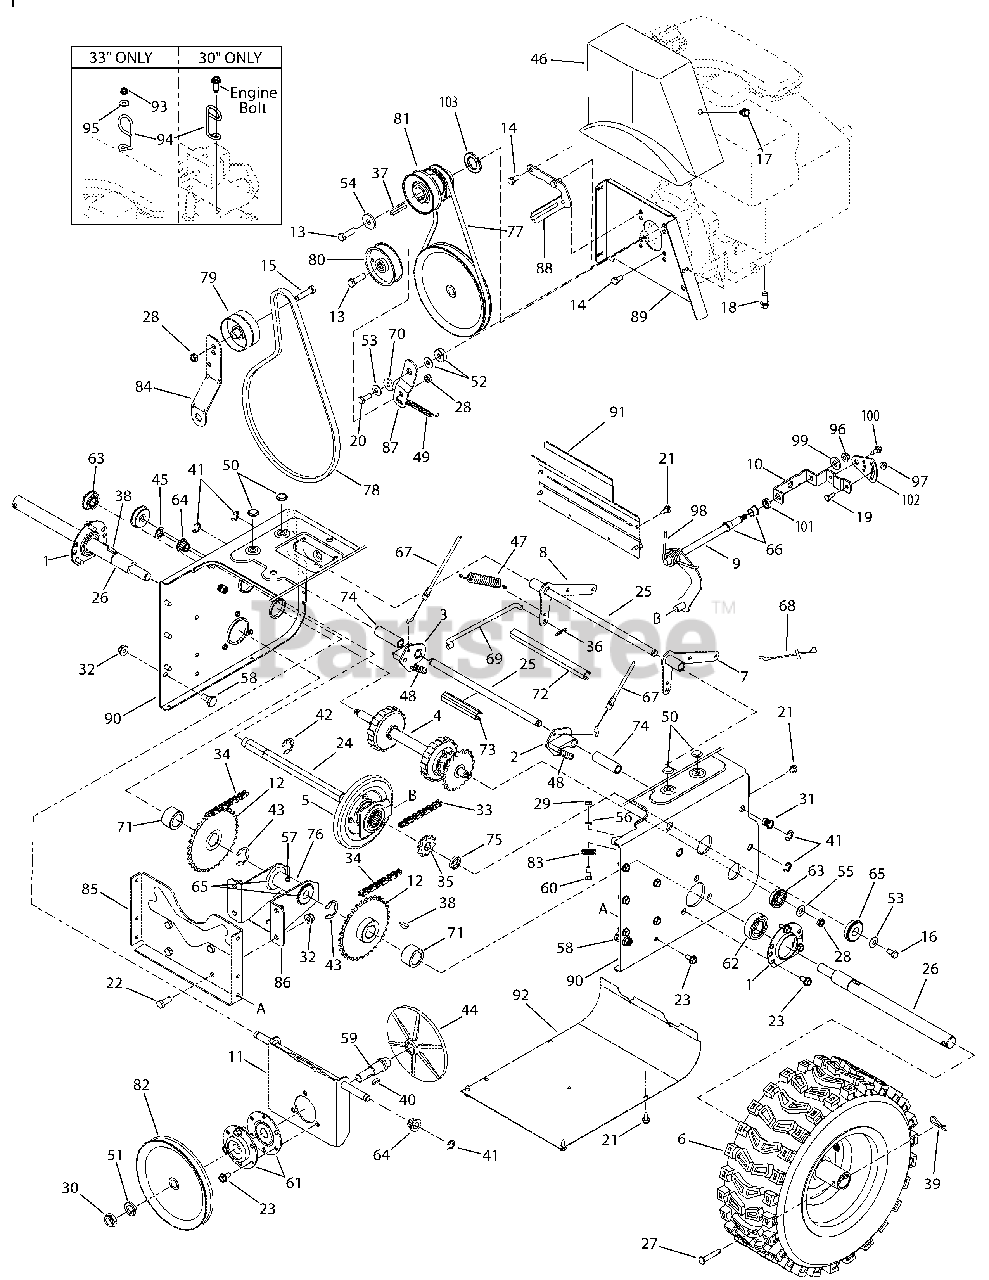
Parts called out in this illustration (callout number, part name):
1	Housing, Bearing
2	Dogg, Steering Drive, LH
3	Dogg, Steering Drive, RH
4	Shaft Assembly, Steering
5	Assembly, Friction Wheel
12	Sprocket, 32T
13	Screw, Hex Cap, 3/8-24 x 1.25 Gr8
14	Screw, Hex Cap, 5/16-24 x .625 Gr5
15	Screw, 3/8-24 x 1.50
16	Screw, Hex Cap Lk, 5/16-18 x .625 Gr5
17	Screw, Hex Tapp, 5/16-18 x .5
18	Screw, Hex Sems Tapp, 3/8-16 x 1.0
19	Screw, Hex, 1/4-20 x .620
20	Scrw, Hx , 5/16-24 x 1.25 Gr5 - 30" ONLY
20	Scrw, Hx Lk, 5/16-24 x .875 Gr8 - 33" ONLY
21	Screw, Hex Wash.
22	Screw, Hex Cap, 3/8-16
23	TT Screw, 5/16-18 x .750
24	Shaft, Hex Drive
25	Shaft, Actuator
26	Axle, Wheel
27	Pin, Clevis
28	Nut, Hex Insert Jam Lock
29	Nut, Hex, 1/4-28 GR5
30	Nut, Hx Insert Jam Lk
31	Nut, Insert 3/8-16
32	Nut, Hx Flnge Insert Lk
33	Chain, Endless, #41 x 36L
34	Chain, #420 x 40L
35	Sprocket, #41 x 10T
36	Pin, Internal Cotter
37	Key, Square, 1/4 x 1.5
38	Key, Woodruff
39	Pin, Internal Cotter
40	Key, Hi-Pro, 3/16 x 5/8
41	E-Ring
42	Ring, Retaining
43	Ring, Retainer
44	Plate, Drive
45	Nut, Speed
46	Cover, Belt
47	Spring, Extension
48	Spring, Extension
49	Spring, Extension, .375 x 3.18
51	Washer, Lock, 5/8
52	Spacer, .331 x 1.01 x .36 - 30" ONLY
52	Washer, Flat, .349 x .879 x .063 - 33" ONLY
53	Washer, Belleville, .34 x .872 x .06
54	Washer, Flat, .406 x 1.25 x .157 HT
55	Wash, .406 x .875 x .059
56	Washer, Lock, 1/4
57	Fitting, Lube, 3/16 Drive
58	Screw, Shldr., .498 x .34
59	Spindle, Drive Plate
60	Screw, Hex Shldr., 1/4-28
61	Ass’y, Bearing/Housing
62	Bearing, Self Aligning
63	Bearing, Ball
64	Bearing, Hex Flange
65	Bearing, Ball
66	Bush, Flg, .5 ID x .627 OD
67	Cable, Steering
68	Cable, Auger Idler
69	Rod, Drive Clutch
70	Spacer, Shoulder
71	Spcr., 1.0 ID x 1.50 OD
72	Spcr., .51 ID x 7.895 Lg.
73	Spcr., .51 ID x 3.66 Lg.
74	Spcr., .514 x .632 x 2.44
75	Spacer, .675 x 1.0 x .23
76	Spcr, .6725 x 1.125 x 2.48
77	V-Belt, 3/8 x 34.4 - 30" ONLY
77	V-Belt, 3/8 x 35.5 - 33" ONLY
78	V-Belt, 1/2 x 42.0 - 30" ONLY
78	V-Belt, 1/2 x 44.0 - 33" ONLY
79	Idler, Flat, 2.75 OD
80	Pulley, Flat Idler, 3.0 OD
81	Pulley, Dbl, 3.25 OD
82	Pulley, Drive
83	Roller, Cable
84	Brkt., Idler, Auger
87	Bracket, Idler, Drive
93	Nut, Flange Lock, 1/4-20 GrF
94	Guide, Control Cable
95	Washer, Flat, .28 x .74 x .063
96	Nut, Hx Flnge Insert Lk, 5/16-18 GrF
97	Nut, Hx Flnge Insert Lk, 1/4-20 GrF
98	Spring, Torsion
99	Washer, Flat, .469 x .875 x .105
100	Screw, Shoulder, .368 x .113:1/4-20 TT
101	Spacer, .5151 x .75 x .22
103	Spacer, 1.02 x 1.63 x .1425 - 30" ONLY
